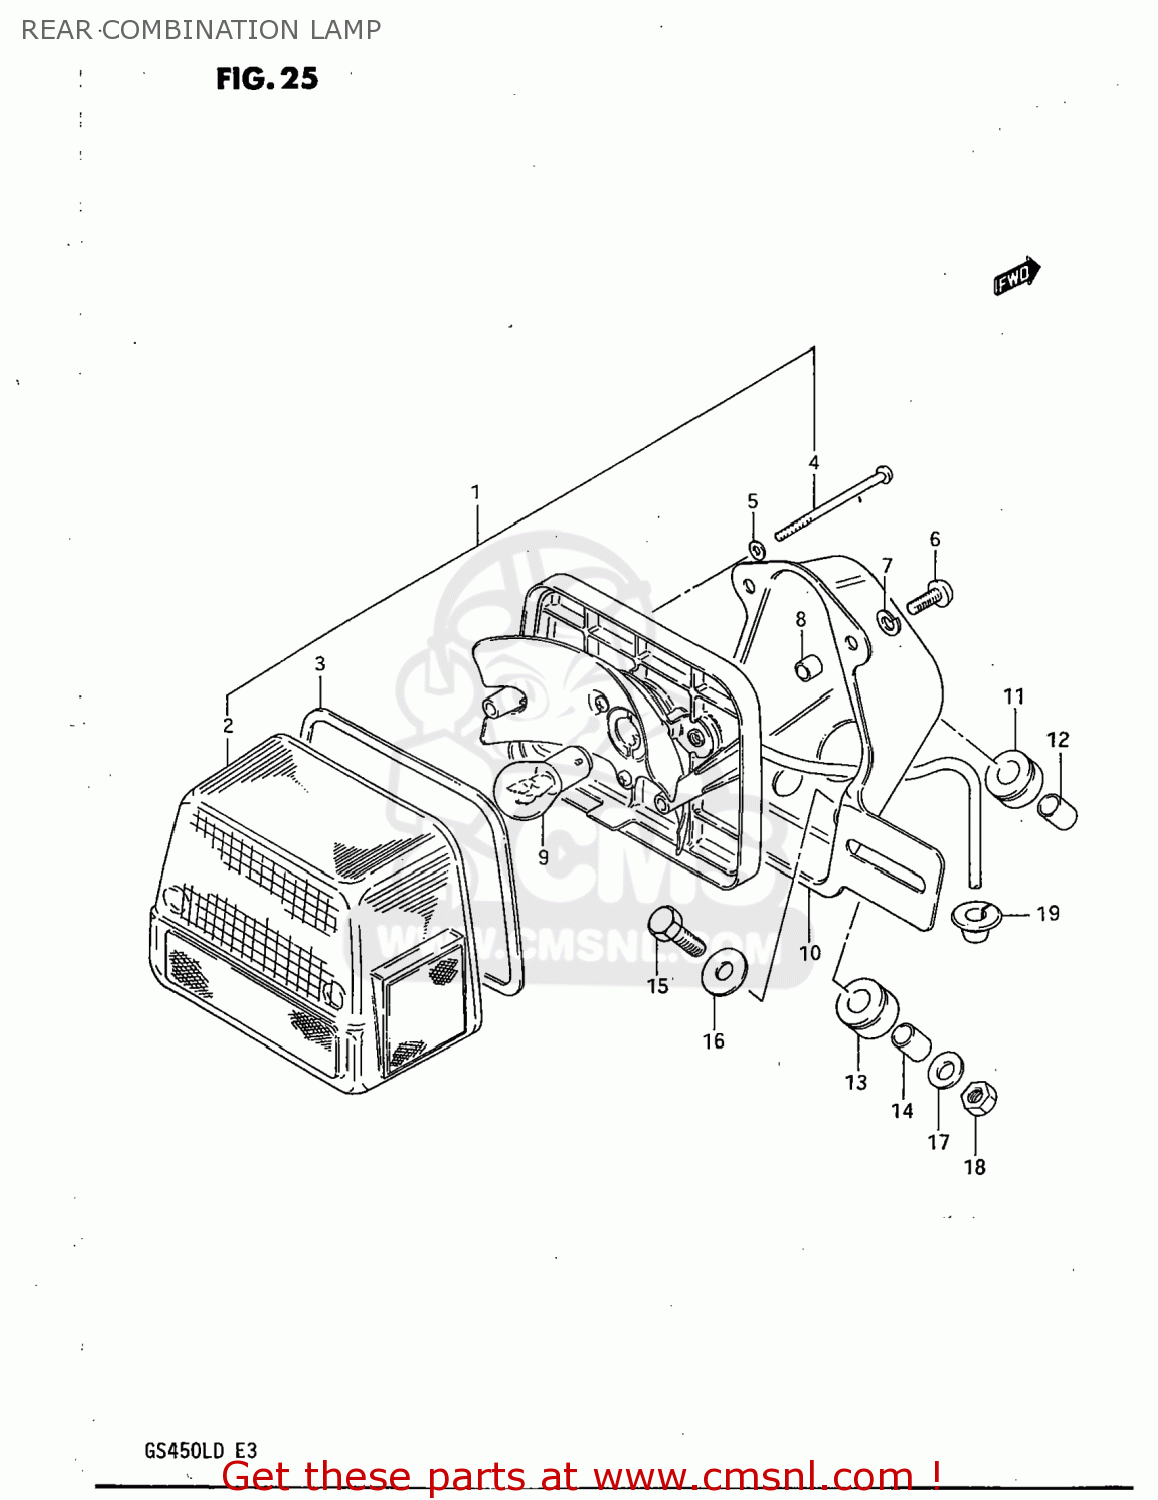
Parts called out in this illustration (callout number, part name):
1	LAMP UNIT,RR COMBNATION
2	LENS
3	GASKET (NAS)
4	SCREW
5	GASKET (NAS)
6	SCREW
7	LOCK WASHER
8	SPACER
9	BULB(12V23W)
10	BRACKET,REAR COMBINATION LAMP
11	CUSHION
12	SPACER
13	CUSHION,REAR COMBINATION LAMP
14	SPACER,REAR COMBINATION LAMP
15	BOLT
16	WASHER (6.5X20X1.2)
17	WASHER
18	NUT
19	GROMMET
